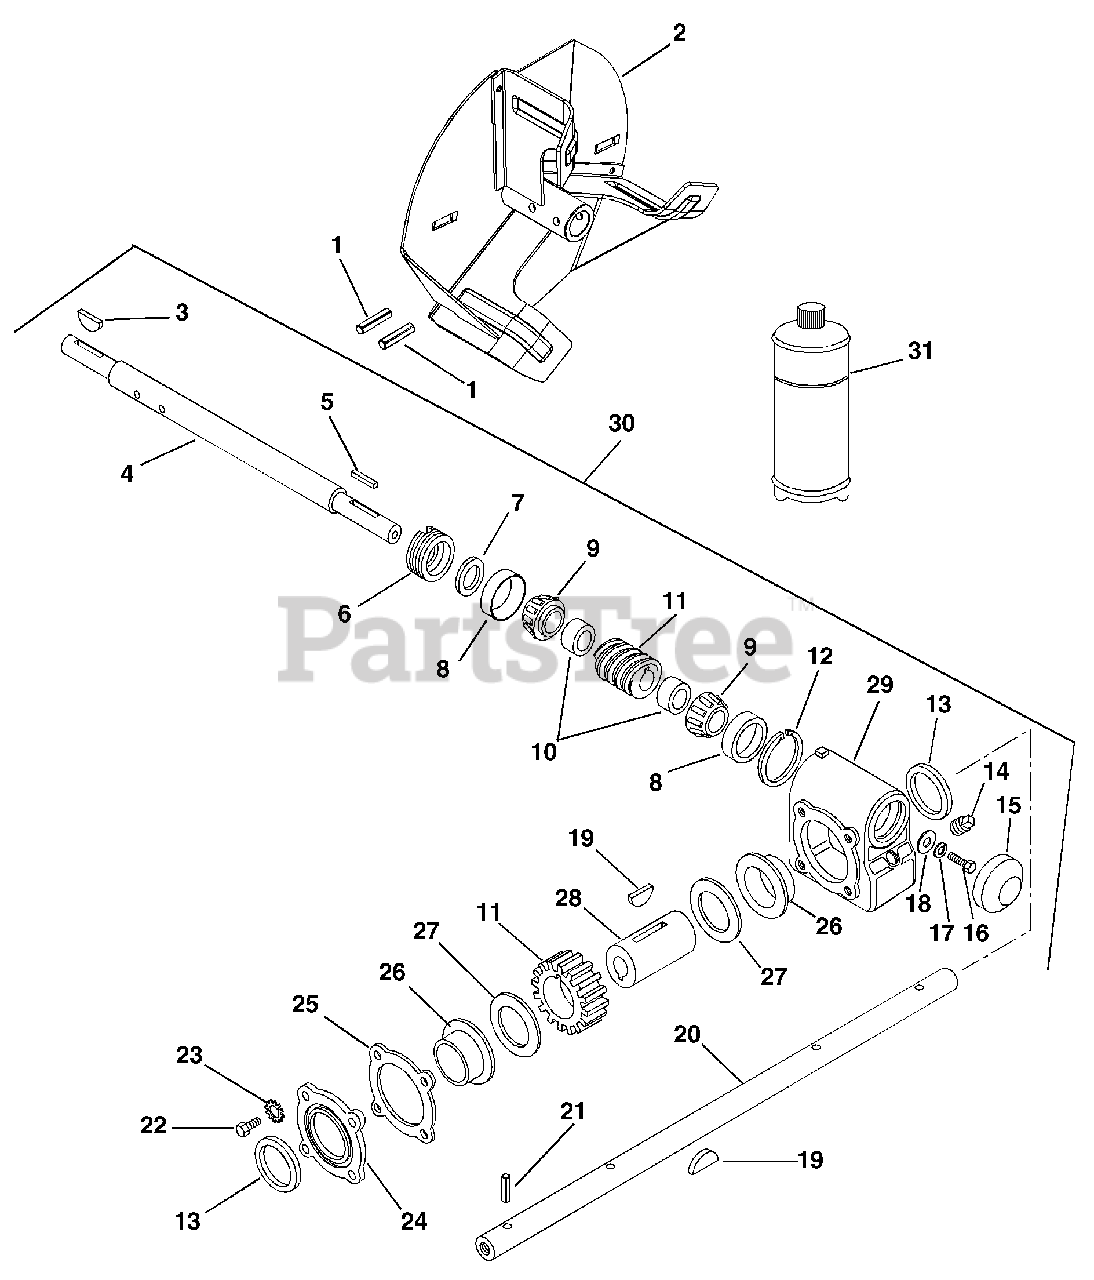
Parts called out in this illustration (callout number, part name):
1	PIN-ROLL .313X1.75
2	IMPELLER - 1 ID X 14 OD
2	IMPELLER - 1.00 ID X 12" OD
3	KEY-WDRF .188X.875X.375 SAE11
4	SHAFT, WORM - 1.00 DIA.
5	KEY-SQ .188X1.0X.188 SAE 8630
6	ADJUSTMENT PLUG - 1" SHAFT
7	SEAL 1.000X1.312X.150
8	BRG-CUP 1.781X.475
9	BRG-CONE .750X.61
10	BSHG, SPCR .755X1.12X.50 PM
11	WORM & GEAR SERVICE ASSEMBLY
12	RG-RTNG-INT 1.781X.062
13	SEAL 1.625X2.125X.250
14	PIPE PLUG
15	DUST CAP
16	@BLT-HEX .31-18X.75 GR5 YWZC
17	WSHR-LK .312X.097 HVY YWZC
18	WSHR-FL-STL .328X1.0X.094 YWZC
19	KEY-WDRF .25X.875X.375 SAE A
20	SHAFT, 24" RAKE - 1.00 DIA.
20	SHAFT, 28" RAKE - 1.00 DIA.
20	SHAFT, 32" RAKE - 1.00 DIA.
20	SHAFT, 36" RAKE - 1.00 DIA.
21	PIN-ROLL .188X1.50
22	@BLT-HEX .25-20X.75 GR5 YWZC
23	@WSHR-LK-EXT.262X.502X.026YWZC
24	GEAR CASE COVER
26	BSHG-FLG .683X1.87X1.68X2.250
27	WSHR-FL-STL 1.625X2.500X.012
28	GEAR CASE SHAFT
29	GEAR CASE - CAST IRON
30	GEAR CASE, CAST IRON
30	GEAR CASE - CAST IRON
31	ARIENS 16 OZ.BOTTLE OF L2 LUBE
